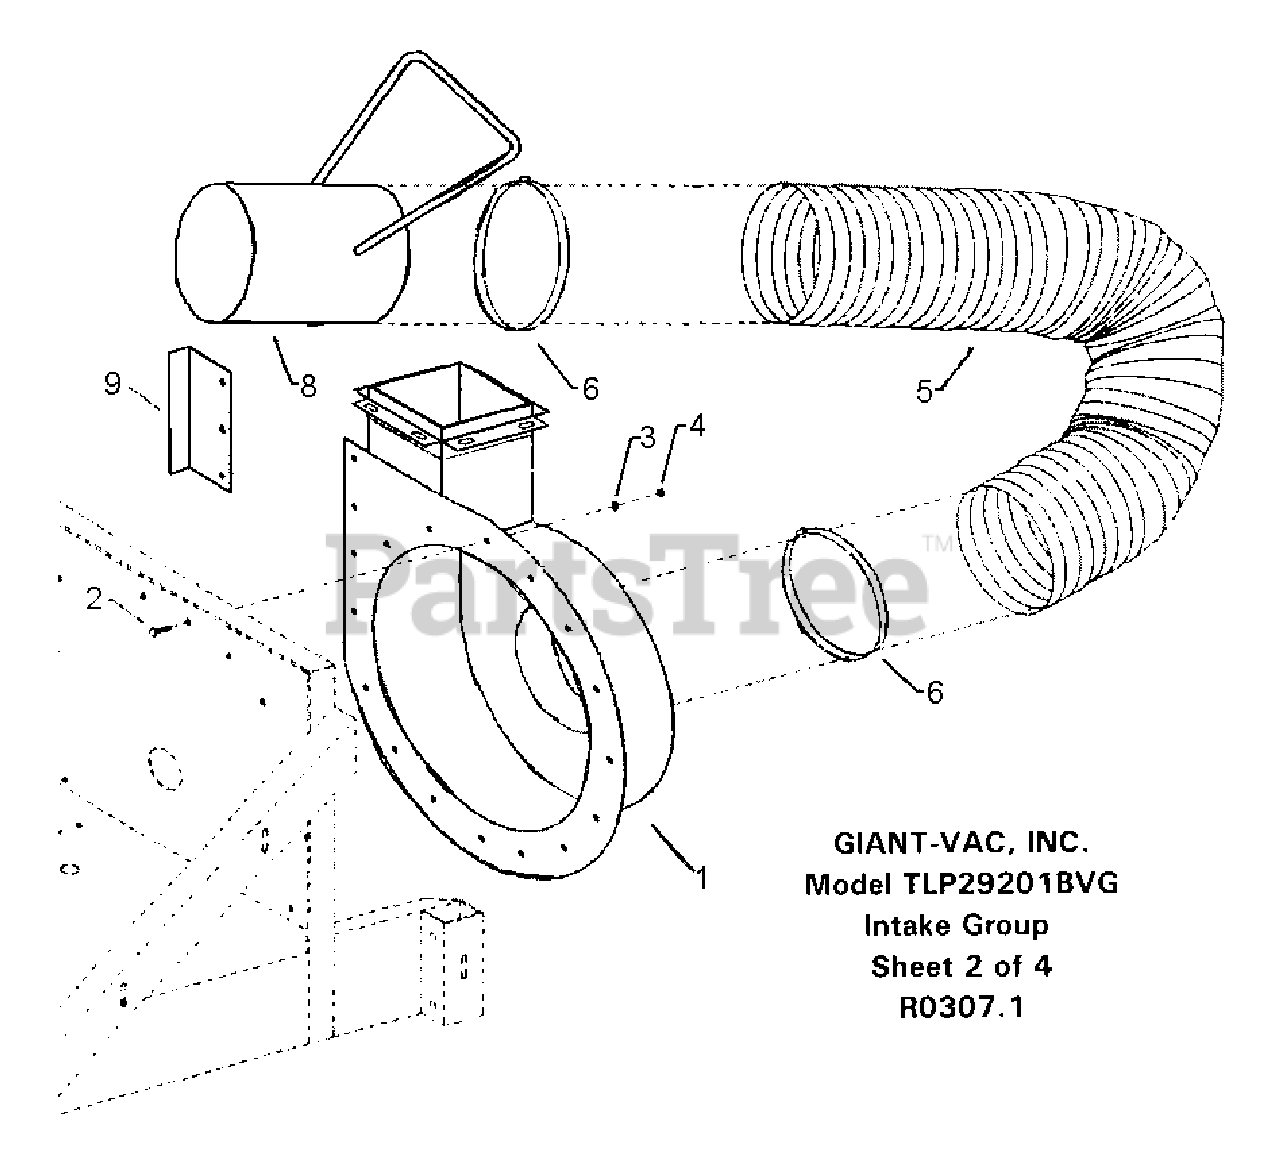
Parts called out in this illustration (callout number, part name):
1	Housing, Impeller
2	3/8-16 x 1" Hex Bolt
3	3/8 Lock Washer
4	3/8-16 Hex Nut
5	Hose, Intake 12" x 10'
6	Clamp, Hose 12"
8	Nozzle, Intake 12"
9	Plate, Hose Protector (CHW Units Only)
